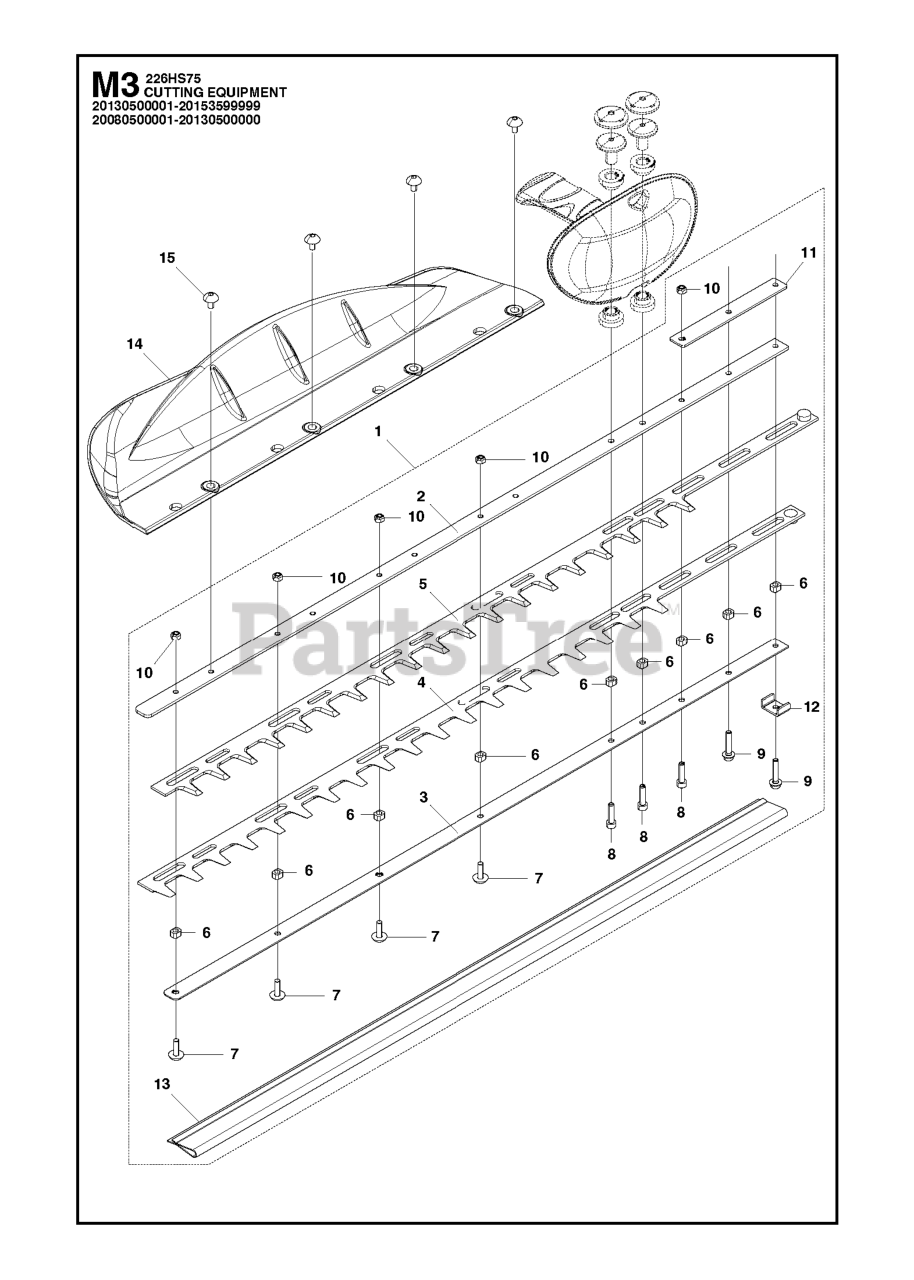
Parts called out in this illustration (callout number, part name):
1	BLADE ASSY
2	PLATE UPPER
3	PLATE LOWER
4	BLADE LOWER
5	BLADE UPPER
